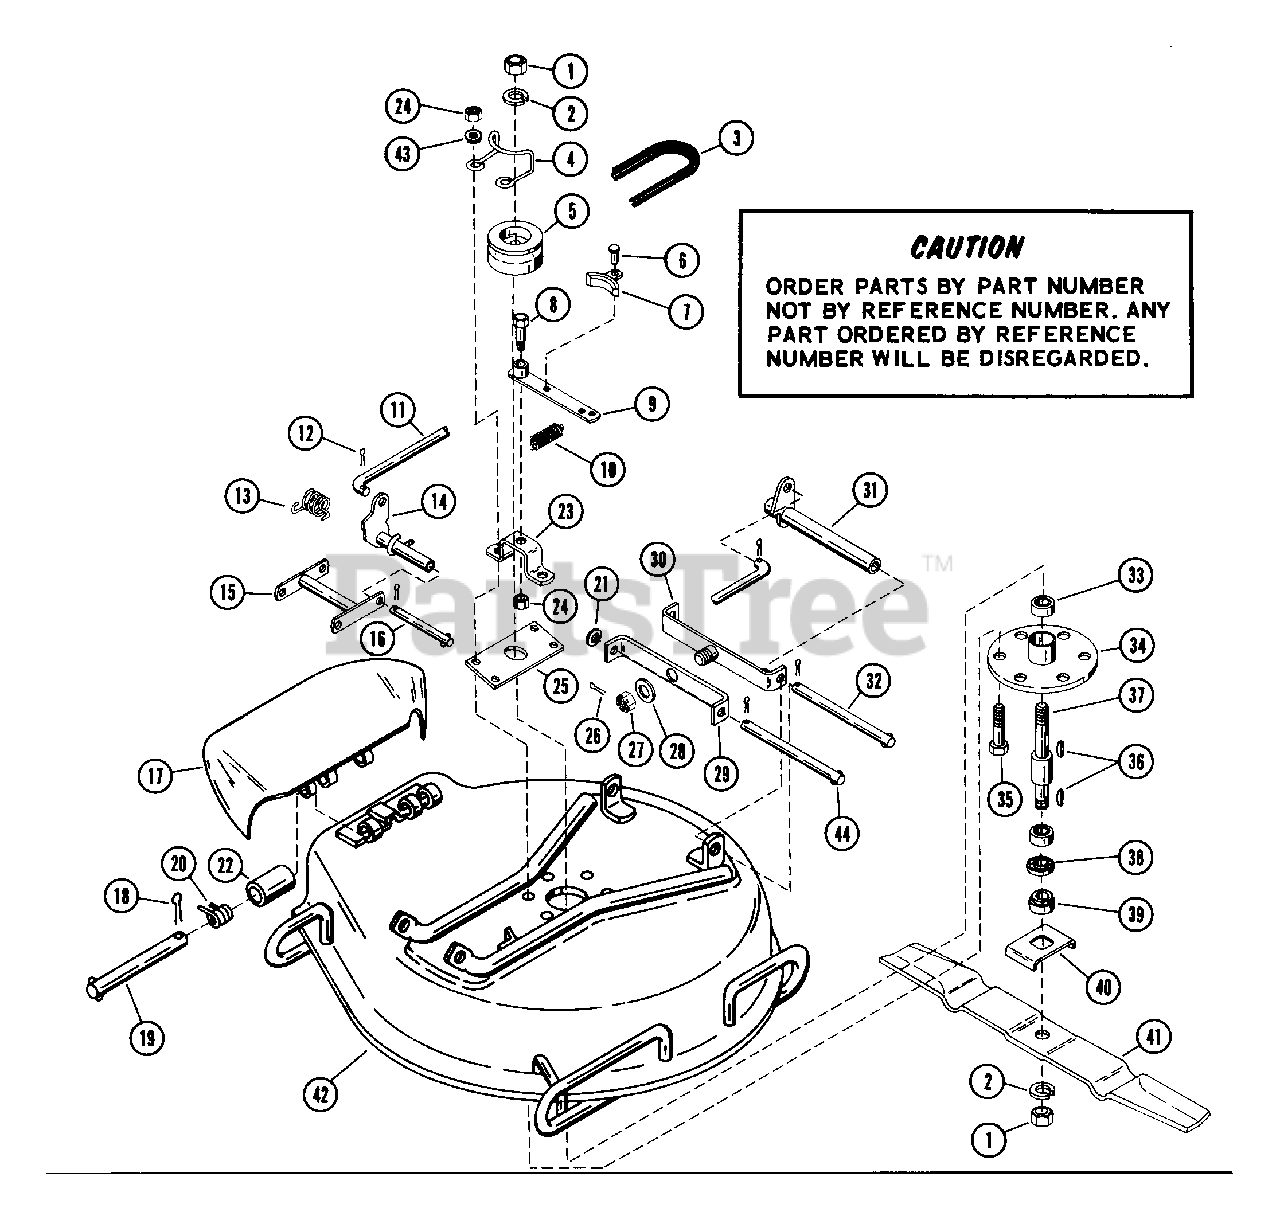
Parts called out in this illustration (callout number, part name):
1	NUT-JAM .75-10 PL
2	WSHR-LK .750X.188 MED PL
3	V-BELT, 5L-RAW EDGE
4	MOWER BELT FINGER
5	MOWER SHEAVE
6	RVT .25X.50 RH ST
7	BLADE BRAKE
8	SHOULDER BOLT .50 X 1.75
9	BLADE BRAKE ARM
10	SG-TENS .072X.51X5.31 WLD 25
11	HEIGHT LINK ROD
12	PIN-COTR .12X1.0 PL
13	SG-TORS .162X.75X.648
14	HEIGHT CONTROL ARM
15	FLOATING LINK
16	ADAPTER PIN
17	PAN CHUTE EXTENSION
18	PIN-COTR .09X.75 PL
19	CLEVIS PIN
20	SG-TORS .095X.50X 1.0
21	WSHR-FL-STL .531X1.062X.095 PL
22	BSHG-SLV .334 X .502 X 1.437
23	BLADE BRAKE SUPPORT
24	NUT-LK-CTR .375-16 GR A PL
26	PIN-COTR .12 X 1.25 PL
27	NUT-JAM-SL .625-18
28	WSHR-FL-STL .630X1.005X.062 PL
31	REAR RAISING BRACKET
32	REAR BRACKET PIN
33	BRG-BALL .751X1.78X.61
34	SPINDLE HOUSING
35	BLT-HEX .38-16X1.00 PL
36	KEY-WDRF .188X.75X.313 SAE 9
37	MOWER SPINDLE
38	BEARING SLINGER
39	RETAINER HUB
40	BLADE TRAY
41	BLADE, MOWER
42	MOWER PAN
43	WSHR-FL-STL .38X.875X.083 PL
44	HANGER PIN
